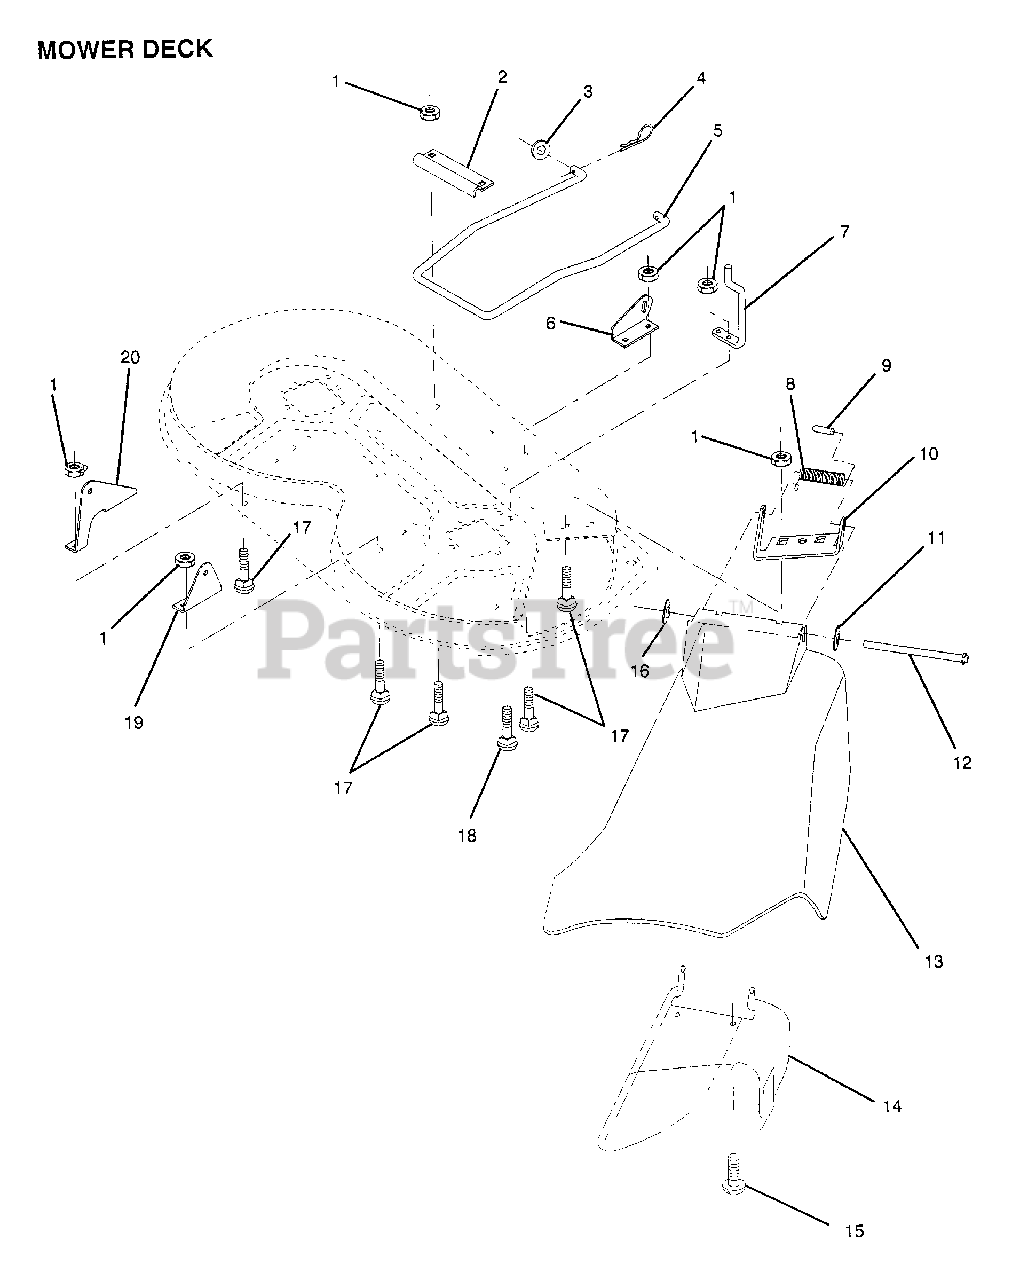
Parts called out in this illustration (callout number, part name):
2	"BRKT,STAB LINK"
4	RETAINER.SPRING
5	STABILIZER MOWER
6	"BRKT,FRT LIFT RH"
7	"GUIDE,FRT MAN RH"
8	SPRING TORSION
9	CAP-SLEEVE LT
11	WASHER
12	HINGE ROD
14	DEFL SUPT ASS'Y
15	SCREW PAN HD
16	NUT PUSH M
17	BOLT
18	BOLT
19	"BRKT,REAR LIFT RH"
20	"BRKT,REAR LIFT LH"
